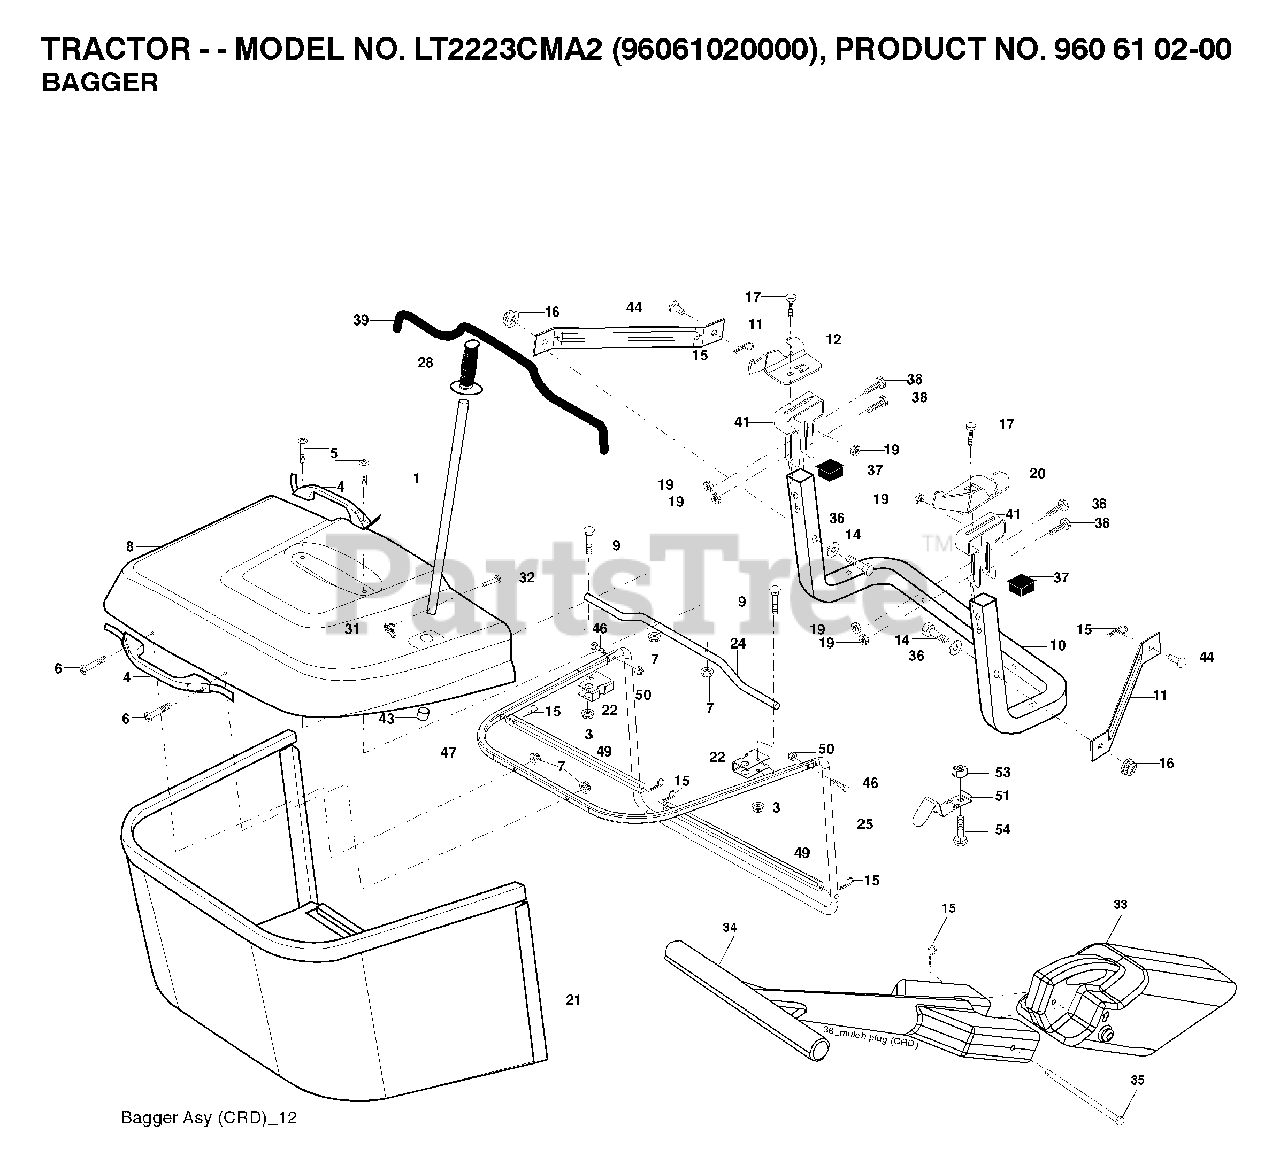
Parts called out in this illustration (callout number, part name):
1	TUBE HANDLE
3	NUT T
5	SCREW.PAN.HEAD
11	BRACKET
14	BOLT-HEX EAK
15	RETAINER-SPRNG RB
16	NUT LOCK FLG 3/8-16 UNC
17	BOLT
19	NUT LOCK HEX FLANGE 5/16-18
20	BRKT.PIVOT.RH.CRD
21	BAGGER.ASM.CRD.2007
22	BRACKET
24	TUBE
28	GRIP.HANDLE.BLACK
31	RETAINER CLIP
32	RIVET,DRILLED
33	MULCH PLUG, CTH150
35	PIN
38	BOLT.5/16-18X2.5
41	BRKT, BAGGER
43	PLUG, TUBING END
46	BOLT.CARRIAGE.5/16-18
50	NUT.71038.31-18.HEX.NYLOCK
53	NUT
54	BOLT
